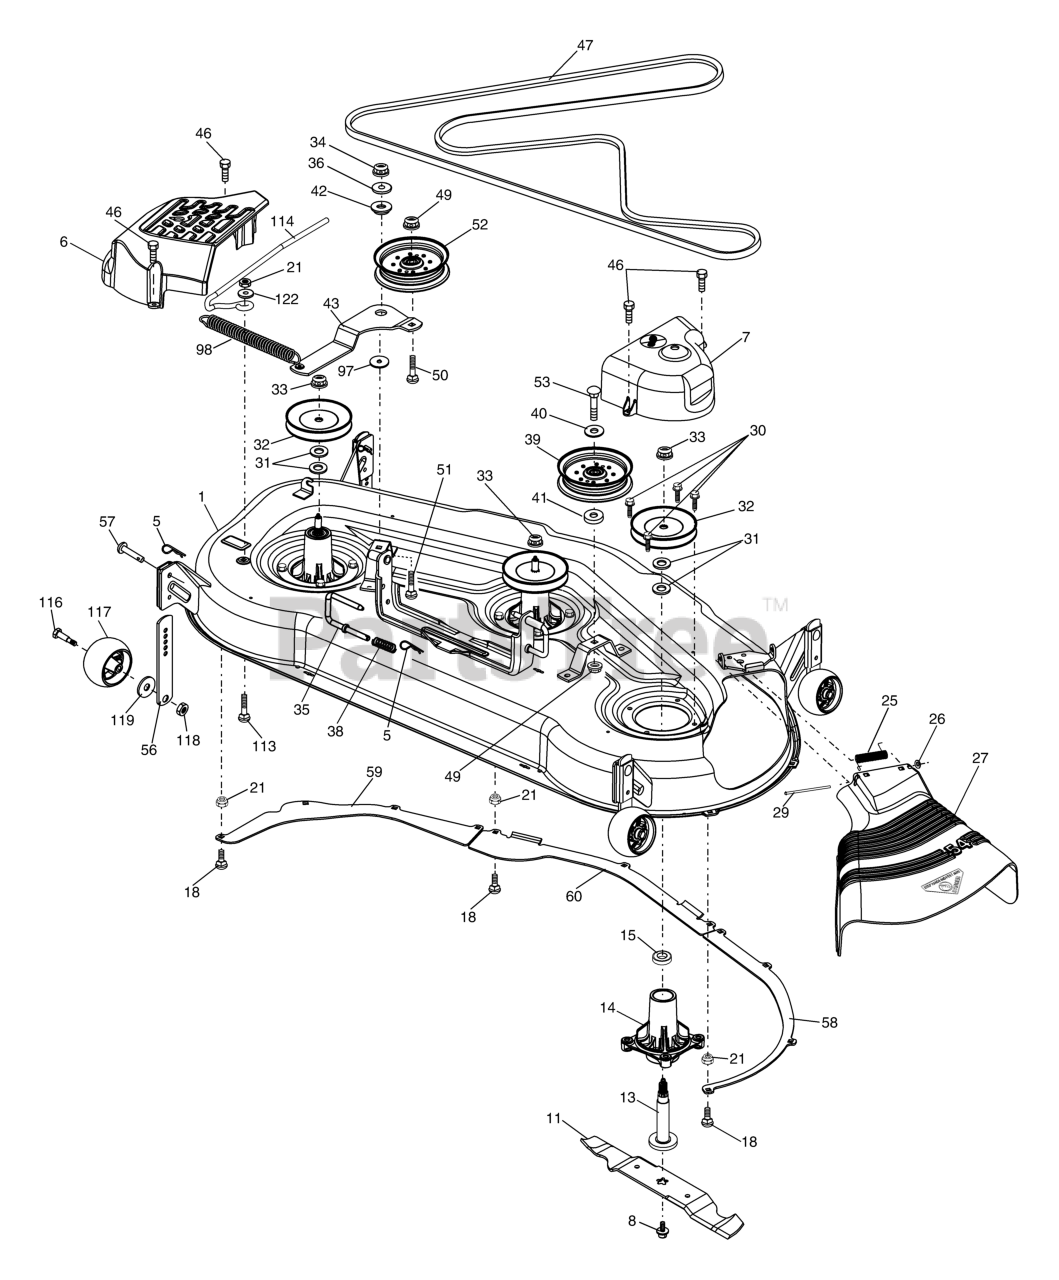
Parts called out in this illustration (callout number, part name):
1	DECK.PNT.WLDMENT.54"
5	RETAINER-SPRNG RB
6	COVER.MANDREL.LH.DECK.54"
7	COVER.MANDREL.RH.DECK.54"
8	BOLT 7/16 ASM BLADE
11	Blade Standard
13	SHAFT ASM MANDREL
14	RP.HOUSING.MANDREL.4PT.
18	BOLT
21	LOCKNUT
25	SPRING, TORSION
26	NUT PUSH M
27	DEFLECTOR
29	ROD.HINGE
30	SCREW, WASHER HEAD
31	WASHER.SPACER.MANDREL
32	PULLEY MANDREL
33	NUT, FLG TOPLOCK 9/16"
35	PIN.SUSPENSION.REAR.54"
36	WASHER
38	SPRING COMPRESSION PULL
39	PULLEY.IDLER.STATIONARY
40	Washer 13/32 x 1-3/8 x 3 Ga.
41	WASHER
42	SPACER RETAINER
43	ARM.IDLER.54"
46	SCREW.1/4-20X5/8
47	V-BELT 54" HIGH PERFORMANCE
49	NUT LOCK FLG 3/8-16 UNC
50	BOLT
51	BOLT
52	IDLER PULLEY
53	BOLT.HEX
56	BAR.ADJUST.WHEEL.ANTI.SCALP.BL
57	RIVET.PIN.HEAD.YELLOW.
58	BAFFLE.RIGHT.54"
59	BAFFLE.LEFT.54"
60	BAFFLE CENTER 54" MOWER
97	WASHER 12/32X2X10GA
98	SPRING.CLUTCH.DRIVE.54
113	BOLT CRT
114	ROD TENSION RELIEF
116	BOLT.SHOULDER.3/8-16X3-5/8.
117	RP WHEEL. GUAGE RALLY
118	LOCKNUT
119	WASHER.5/16.FLAT.STE.STD.
122	BUSHING.RELIEF.TENSION
